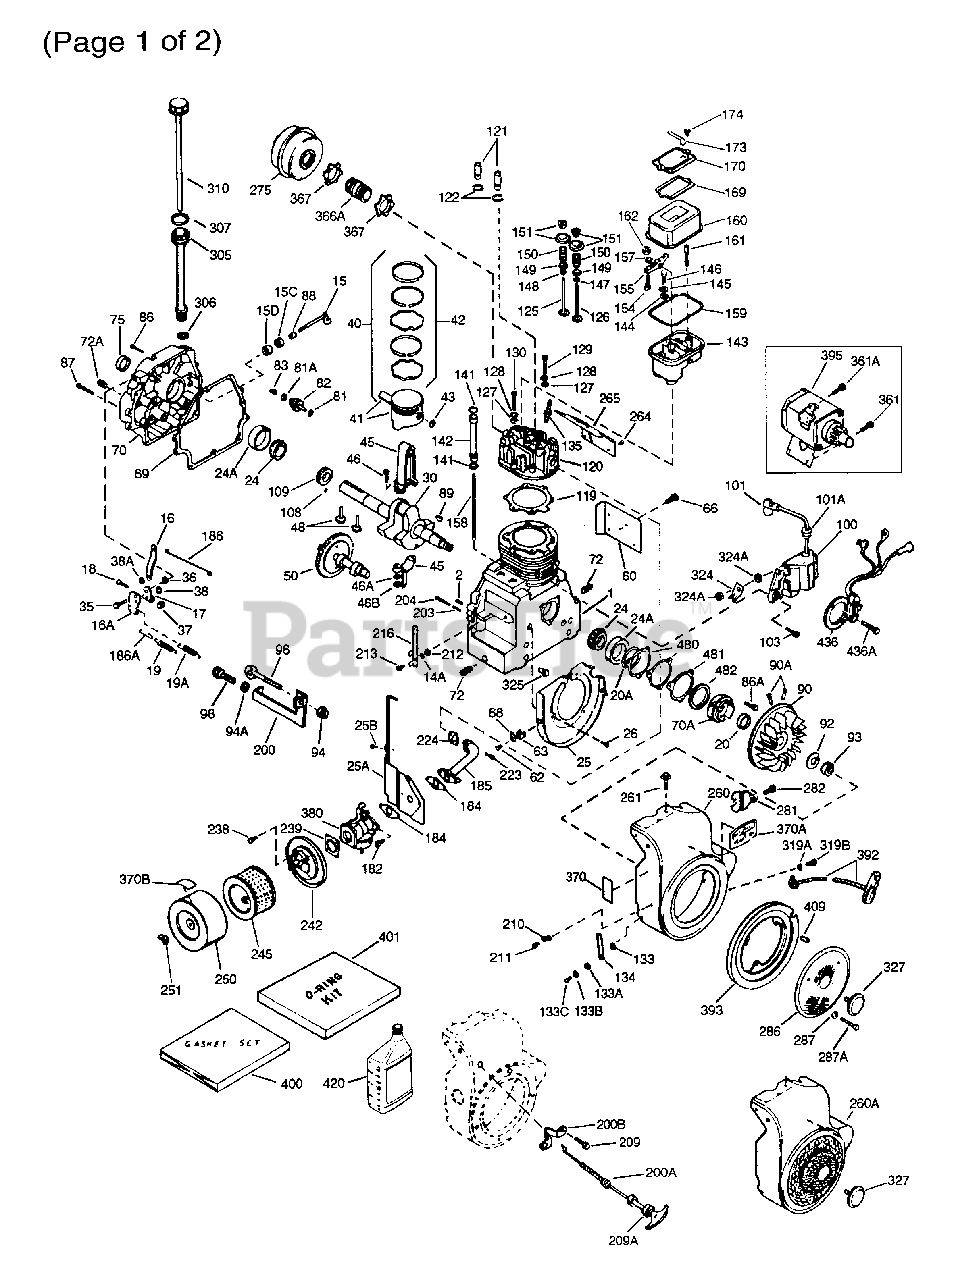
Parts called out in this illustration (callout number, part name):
1	"Cylinder (Incl. 2, 20 & 72)
2	Dowel Pin
15	Governor Rod
15C	Needle Roller Bearing
15D	Needle Roller Bearing
16	Governor Lever
16A	Goveror Spring Plate
17	Governor Lever Clamp
18	Screw, 10-24 x 7/8"
19A	Extension Spring
20	* Oil Seal
20A	* "O" Ring
24	Tapered Roller Bearing
24A	Bearing Cup
25	Blower Housing Baffle
25A	Air Baffle
25B	Screw, 1/4-20 x 5/8"
26	Screw, 1/4-20 x 5/8"
30	Crankshaft
35	Screw, 10-32 x 1/2"
36	Flat Washer
37	Lock Nut, 10-24
38	Retaining Ring
40	Piston, Pin & Ring Set (Std.)
40	Piston, Pin & Ring Set (.010" OS)
40	Piston, Pin & Ring Set (.020" OS)
41	Piston & Pin Ass'y. (Std.) (Incl. 43)
41	Piston & Pin Ass'y. (.010" OS) Incl. 43
41	Piston & Pin Ass'y. (.020" OS) Incl. 43
42	Ring Set (Std.)
42	Ring Set (.010" OS)
42	Ring Set (.020" OS)
43	Piston Pin Retaining Ring
45	Connecting Rod Ass'y. (Incl.46 - 46B)
45	Connecting Rod Ass'y. (.010" US) Incl . 46-46B
45	Connecting Rod Ass'y. (.020" US) Incl . 46-46B
46	Connecting Rod Bolt
48	Valve Lifter
50	Camshaft (MCR)
60	Blower Housing Extension
62	Screw, 8-32 x 3/8"
63	Breather Tube Grommet
68	Ground Terminal
69	* Cylinder Cover Gasket
70	Cylinder Cover (Incl. 15,38,72,75,88)
70A	Cylinder Cover (See Ref. #'s 480-482)
72	Oil Drain Plug
75	Oil Seal
82	Governor Gear Ass'y.
83	Governor Spool
86	Screw, 1/4-20 x 2"
86A	Screw, 5/16-18 x 7/8"
87	Screw, 1/4-20 x 1"
89	Flywheel Key
90	Flywheel (Incl. 90A)
90A	Trigger Pin Kit
92	Washer
93	Flywheel Nut
94	Lock Nut, 10-32
98	Governor Spring Adjusting Bolt
98	Screw, 1/4-20 x 1-1/4"
100	Solid State Ignition
101	Spark Plug Cover
101A	Grommet
103	Screw, 1/4-20 x 3/4"
108	Pin, Crankshaft gear
109	Crankshaft Gear
119	* Cylinder Head Gasket
120	Cylinder Head
121	Valve Guide Kit (Incl. 2 of 122)
122	Retaining Ring
125	Exhaust Valve (Std.) (Incl. 151)
125	Exhaust Valve (1/32" OS) (Incl. 151)
126	Intake Valve (Std.) (Incl. 151)
126	Intake Valve (1/32" OS) (Incl. 151)
128	Belleville Washer
129	Screw, 5/16-18 x 1-3/4"
130	Screw, 5/16-18 x 1-3/8"
133	Lock Washer, 5/16
133C	Screw, 5/16-24 x 9/16"
134	Shorting Clip
135	Resistor Spark Plug (RL82C)
141	* "O" Ring (Also Incl. in 401)
142	Push Rod Tube
143	Rocker Arm Housing
144	* "O" Ring (Also Incl. in 401)
146	Screw, 1/4-20 x 29/32"
147	* "O" Ring (Also Incl. in 401)
148	* "O" Ring (Also Incl. in 401)
149	Valve Spring Cap
150	Valve Spring
151	Valve Spring Keeper
154	Rocker Arm Stud
155	Rocker Arm
157	Retaining Ring
158	Push Rod
159	* "O" Ring (Also Incl. in 401)
160	Rocker Arm Housing
161	Screw, 1/4-20 x 3/4"
162	Nut, 1/4-20
169	* Valve Cover Gasket (Also Incl.in 401)
170	Breather Body
173	Breather Tube
174	* Screw, 10-32 x 5/8" Also Incl. in 40 1
182	Screw, Torx T-30, 5/16-18 x 1-1/8"
184	* Carburetor To Intake Pipe Gasket
185	Intake Pipe
186	Governor Link
186A	Governor Lever To Throttle Lever Link
200	Control Bracket
203	Compression Spring
204	Screw, 10-24 x 2"
212	Bushing
213	Screw, 10-24 x 5/8"
216	Control Lever
223	Screw, 5/16-18 x 7/8"
238	Screw, 10-32 x 5/8"
239	* Air Cleaner Gasket
242	Air Cleaner Bracket
245	Air Filter
250	Air Cleaner Cover
251	Wing Nut, 1/4-20
260	Blower Housing
261	Screw, 1/4-20 x 7/16"
261A	Screw, 1/4-20 x 7/16"
264	Screw, 10-16 x 3/8"
265	Cylinder Head Cover
281	Starter Bubble Cover
282	Screw, 8-18 x 7/16"
286	Starter Screen
287	Lockwasher
287A	Screw, 1/4-20 x 1-1/2"
303	Fuel Fitting
305	Oil Fill Tube
307	"O" Ring
310	Dipstick
319A	Lock Washer
319B	Screw, 5/16-24 x 3/8"
324	Terminal
324A	Nut, 8-32
325	Wire Clip
355	Starter Handle
370	Instruction Decal
370A	Decal - XL/C Industrial/Commercial
370B	Decal - Important Lubrication - SAE 3
380	Carburetor (Incl. 184)
392	Starter Rope
393	Starter Rope Pulley
400	* Gasket Set (Incl. items marked PK in notes) Incl. part #'s 29673 (1), 3010 2 (2), 31950 (2), 31956B (1), 31958A (1), 31971 (2), 31972 (1), 32031 (1), 32599 (1), 33476A (2), 33481 (4), 33 484 (3), 33487 (1), 33509 (1), 33515A (1), 34225A (1), 34302A
401	* "O" Ring Set (Also Incl. in 400) 3010 2 (2), 31958A (1), 33481(4), 33484 (3 ), 33487 (1), 33509 (1) 34410 (1)
420	SAE 30 4-Cycle Engine Oil (Quart)
436	Stator Plate Ass'y.
436B	Screw, 10-32 x 5/8"
480	* Shim Gasket (.004/.005) See Repair M anual
481	* Shim Gasket (.005/.007) See Repair M anual
482	* Steel Spacer (.010) See Repair Manua l
